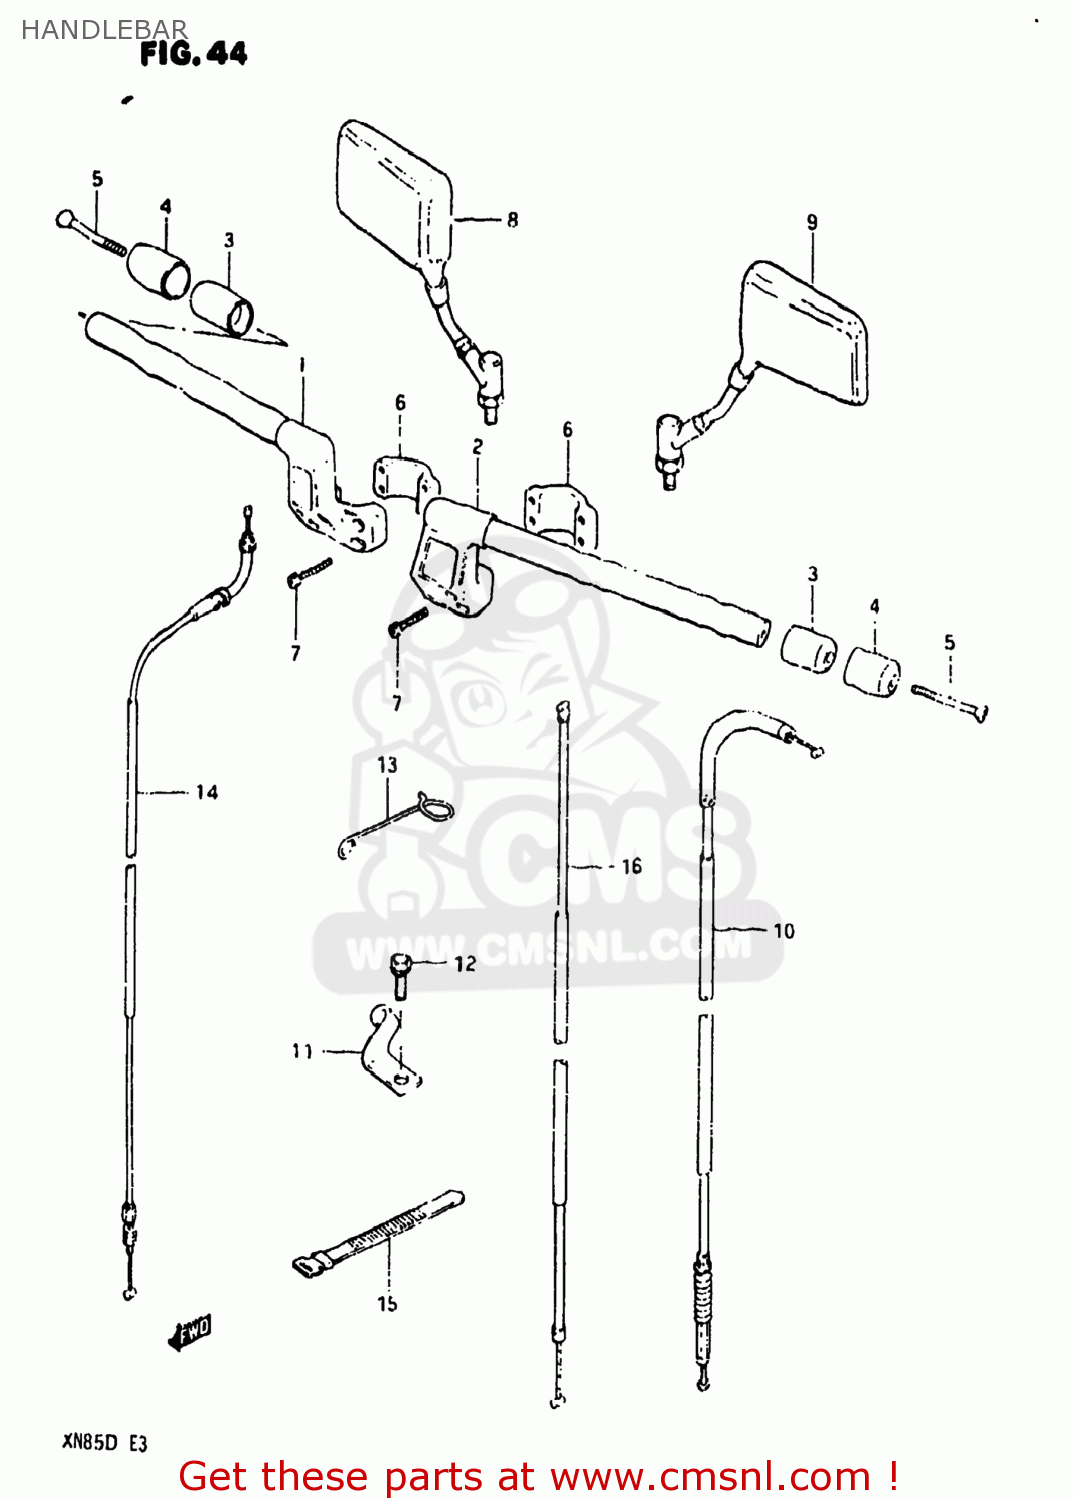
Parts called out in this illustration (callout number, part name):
1	HANDLEBAR,RIGHT
2	HANDLEBAR,LEFT
3	BALANCER,HANDLEBAR
4	CAP,BALANCER
5	SCREW (L:50)
6	HOLDER,HANDLEBAR
7	BOLT
8	MIRROR ASSEMBLY,REAR VIEW
9	MIRROR ASSEMBLY,REAR VIEW
10	CABLE ASSEMBLY,CLUTCH
11	STOPPER,CLUTCH CABLE
12	BOLT
13	GUIDE,CLUTCH CABLE
14	CABLE ASSEMBLY,THROTTLE
15	CLAMP(L:80)
16	CABLE ASSEMBLY,STARTER
